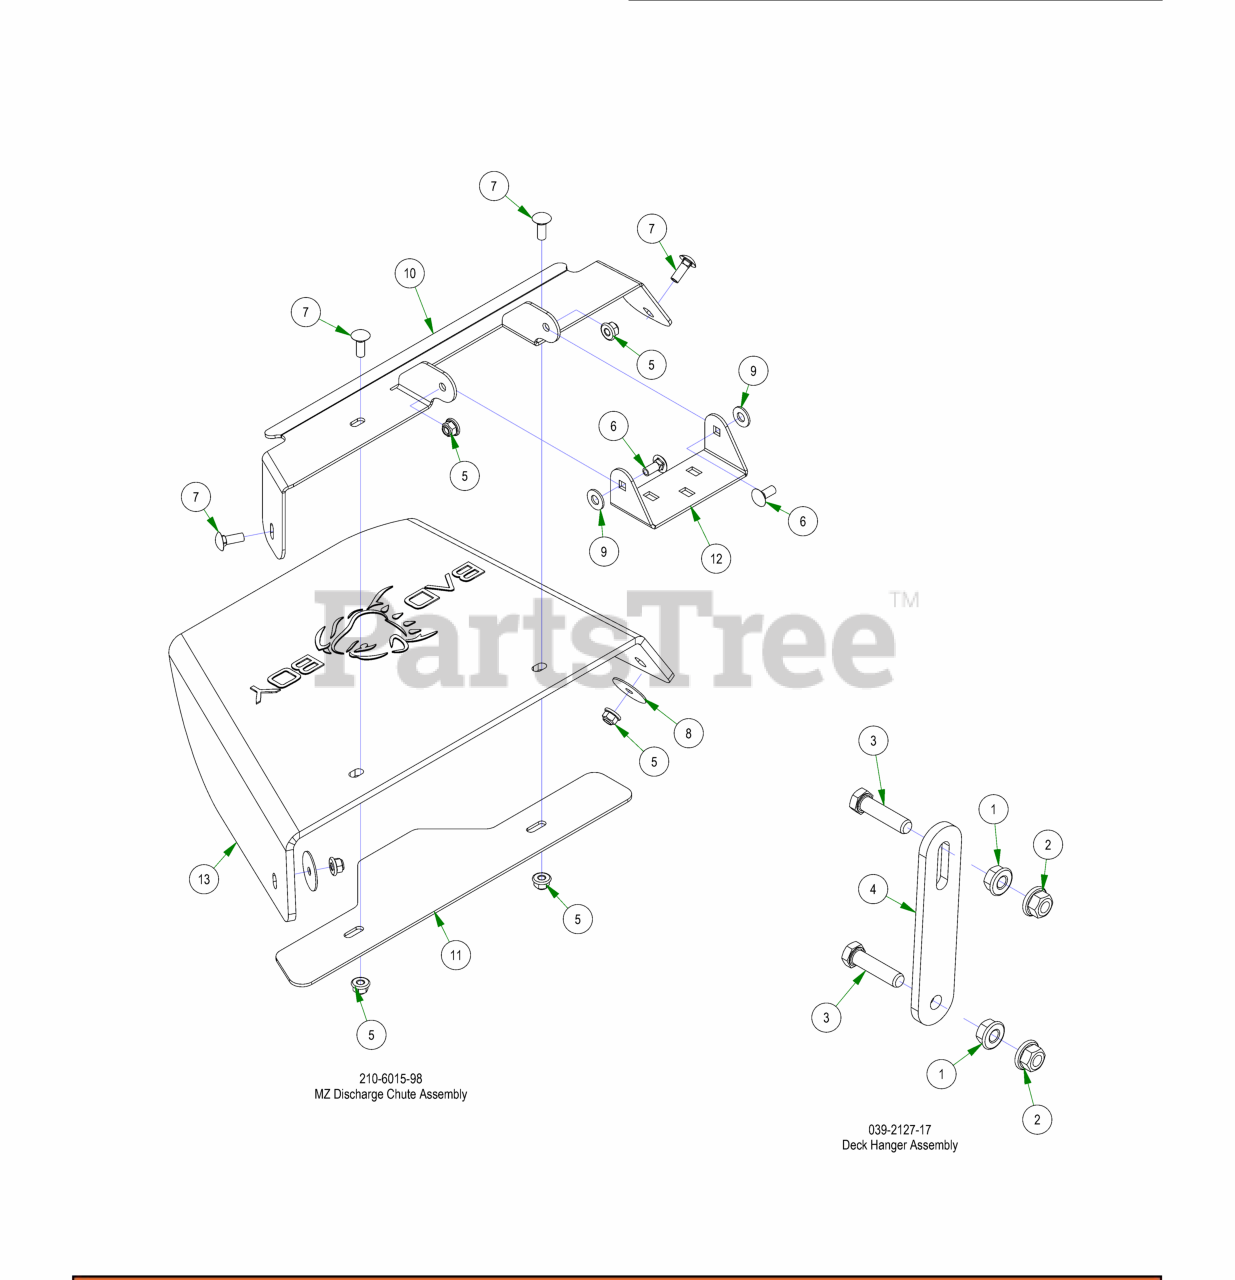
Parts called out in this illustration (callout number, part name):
1	3/8-16 HEX SERRATED FLANGE NUT HARD/ZINC
2	3/8-16 NYLON INSERT FLANGE LOCKNUT (GR.F) ZINC
3	3/8-16 X 1-1/2 HEX CAP SCREW (GR.5) ZINC
4	2017 MZ/ZT Deck Hanger
5	5/16" Nylon Flange Nut
6	5/16-18 x 3/4 Carriage Bolt
7	5/16-18 X 7/8 CARRIAGE BOLT ZINC
8	5/16 Fender Washer
9	.360 ID Plastic Washer
10	Discharge Chute Bracket 48 MZ (Upper)
11	2017 MZ Discharge Chute Bracket-Lower
12	Chute Hanger 48 MZ
13	Rubber Discharge Chute MZ (Component)
